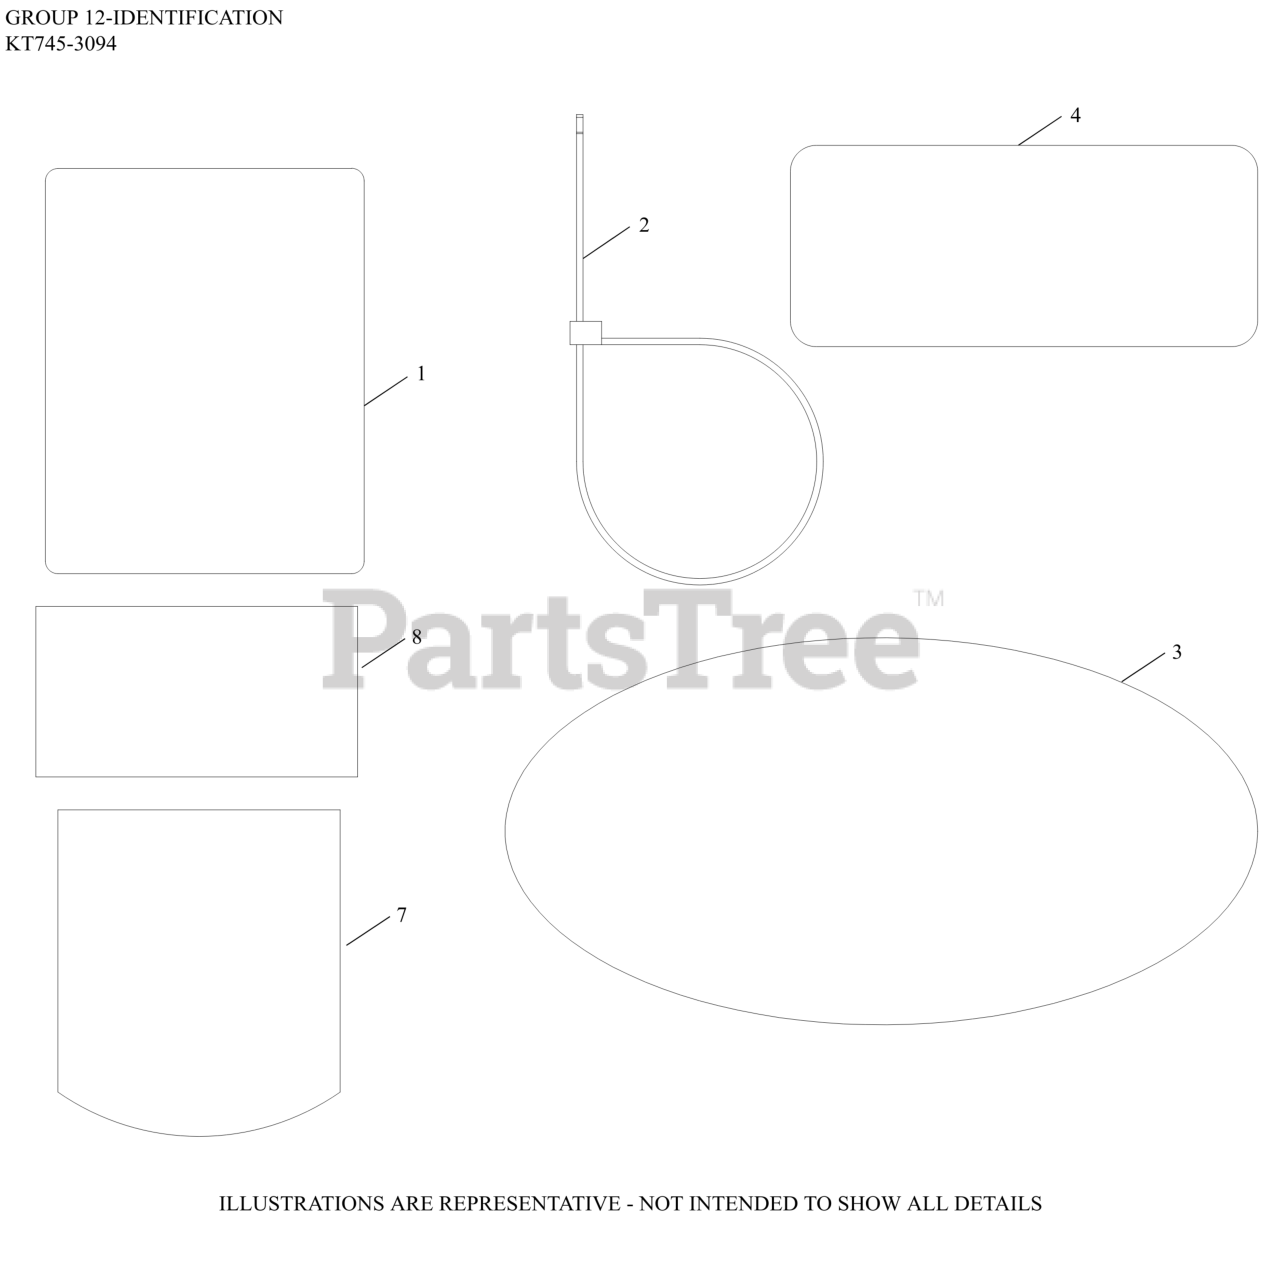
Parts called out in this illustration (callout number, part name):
1	LABEL, CLEAR LAMINATION
3	LABEL, PRO PERFORMANCE FILTRATION SYSTEM
4	LABEL, CANADIAN COMPLIANCE
7	LABEL, 7000 SERIES KT745 (26 HP,PRO A/F)
8	DECAL, USA
